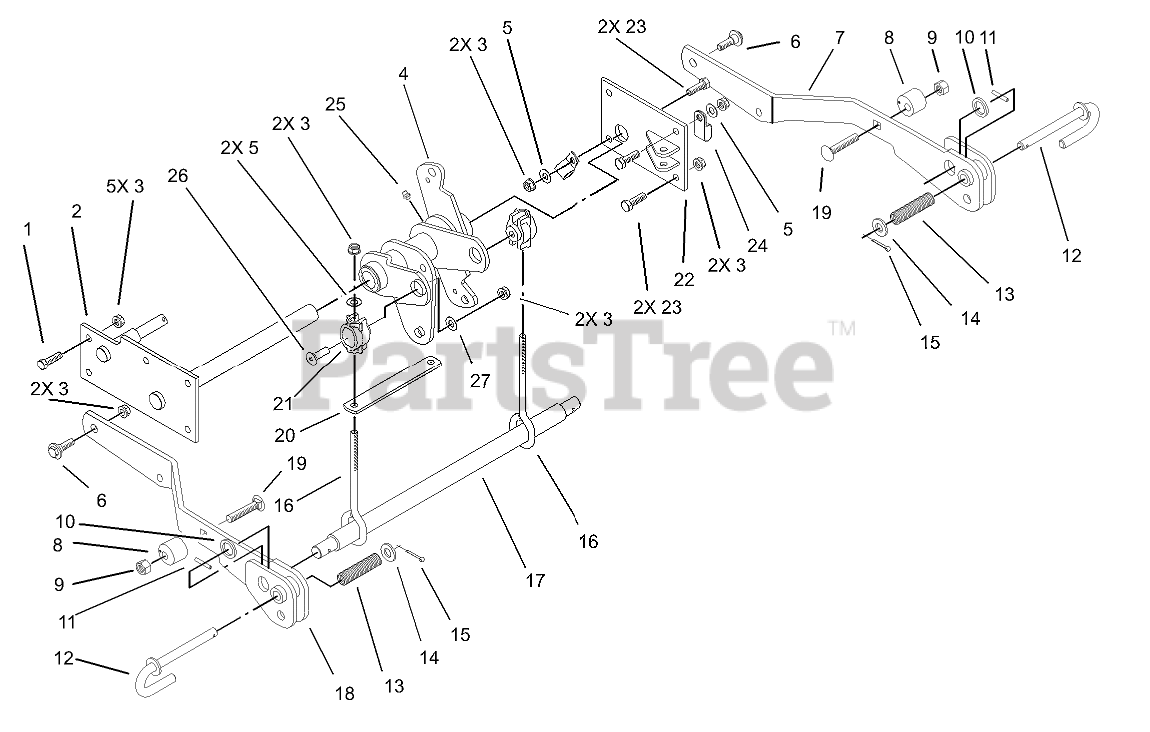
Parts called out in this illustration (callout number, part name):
1	SCREW-HH
2	SUPPORT-LIFT, DECK
3	NUT-LOCK, NI
4	BELLCRANK AND BUSHING ASM
5	WASHER-FLAT
6	BOLT-SHOULDER
7	ARM-LIFT, LH
8	STOP-LIFT, ADJ.
9	NUT-LOCK, NI
10	WASHER-FLAT
11	PIN-ROLL
12	PIN - J
13	SPRING-COMPRESSION
14	WASHER-FLAT
15	PIN-COTTER
16	ROD-LIFT
17	BAR-LIFT
18	Arm-Lift, RH
19	SCREW-CARR
20	SPACER-STRAP
21	SLEEVE-LIFT
22	PLATE - LH SUPPORT
23	SCREW-HH
24	CLAMP-TUBE
25	FITTING-GREASE
26	SCREW-HSFH
27	WASHER-FLAT
